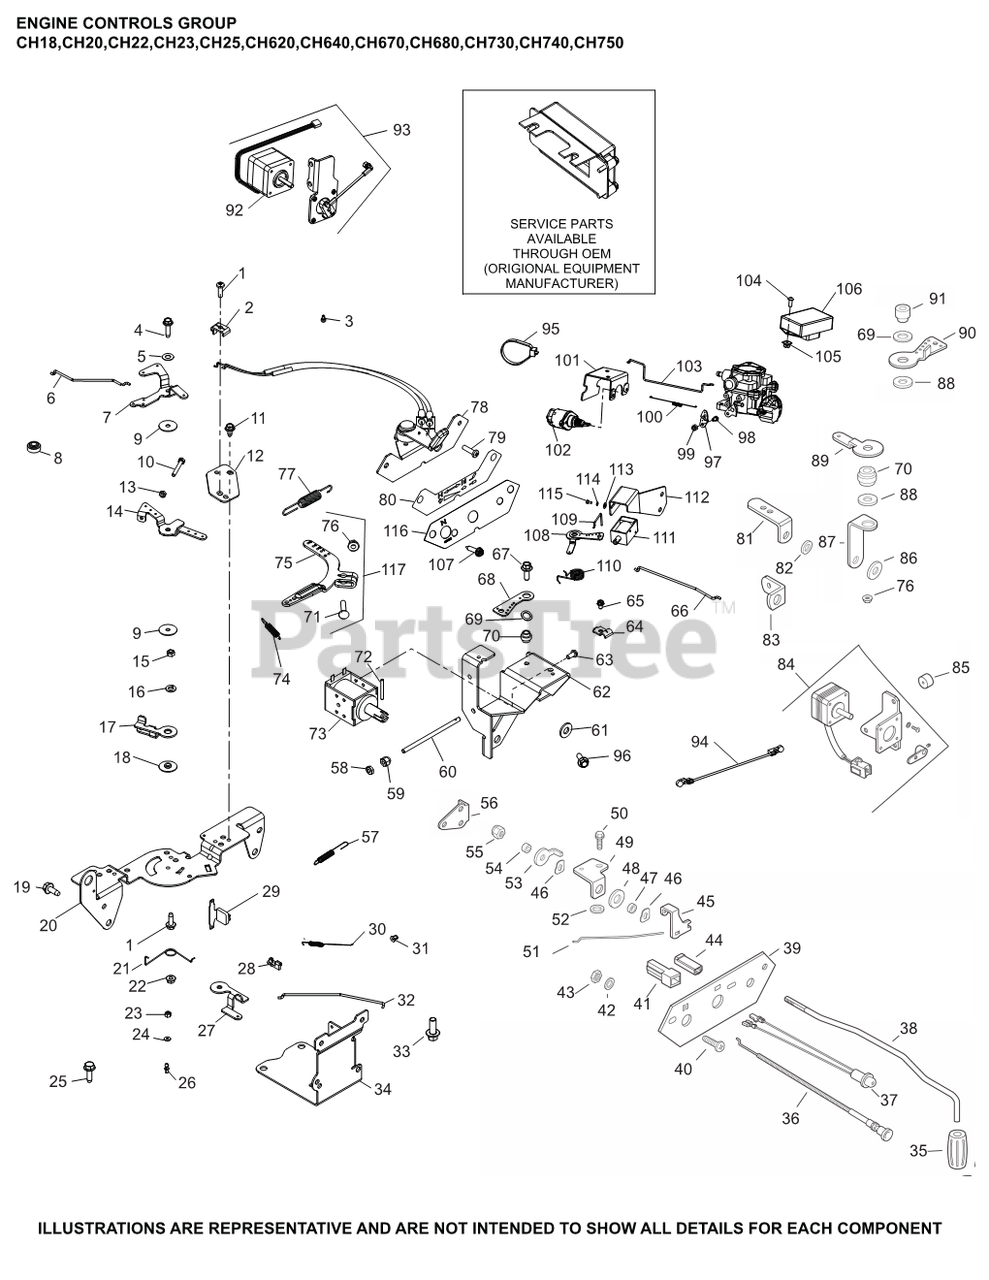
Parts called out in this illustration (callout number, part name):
1	SCREW, THREAD FORMING
2	CLAMP, CABLE
4	SCREW, THREAD FORMING - USE 25 086 473-S
5	WASHER, SPRING 1/4"
6	LINKAGE, CHOKE
7	LEVER, CHOKE
9	WASHER, FLAT 5.5 MM
10	SCREW, CAP M4X.7X30
13	NUT, M4X0.7
14	LEVER, THROTTLE CONTROL
15	NUT, FLG M5X.8
16	WASHER, SPRING LOCK 1/4"
17	LEVER, THROTTLE ACTUATOR
19	SCREW, THREAD FORMING
20	BRACKET, CONTROL
21	SPRING, CHOKE RETURN
22	NUT, LOCK M5X.8
28	BUSHING, THROTTLE LINKAGE
30	SPRING, LINKAGE
31	BUSHING, LINKAGE RETAINING
57	SPRING, THROTTLE LIMITER
66	LINKAGE, THROTTLE
71	BOLT, RD HD SQ NECK M6X1.0X25
75	LEVER, GOVERNOR ASSEMBLY
76	NUT, FLG M6X1.0
77	SPRING, GOVERNOR (PURPLE)
